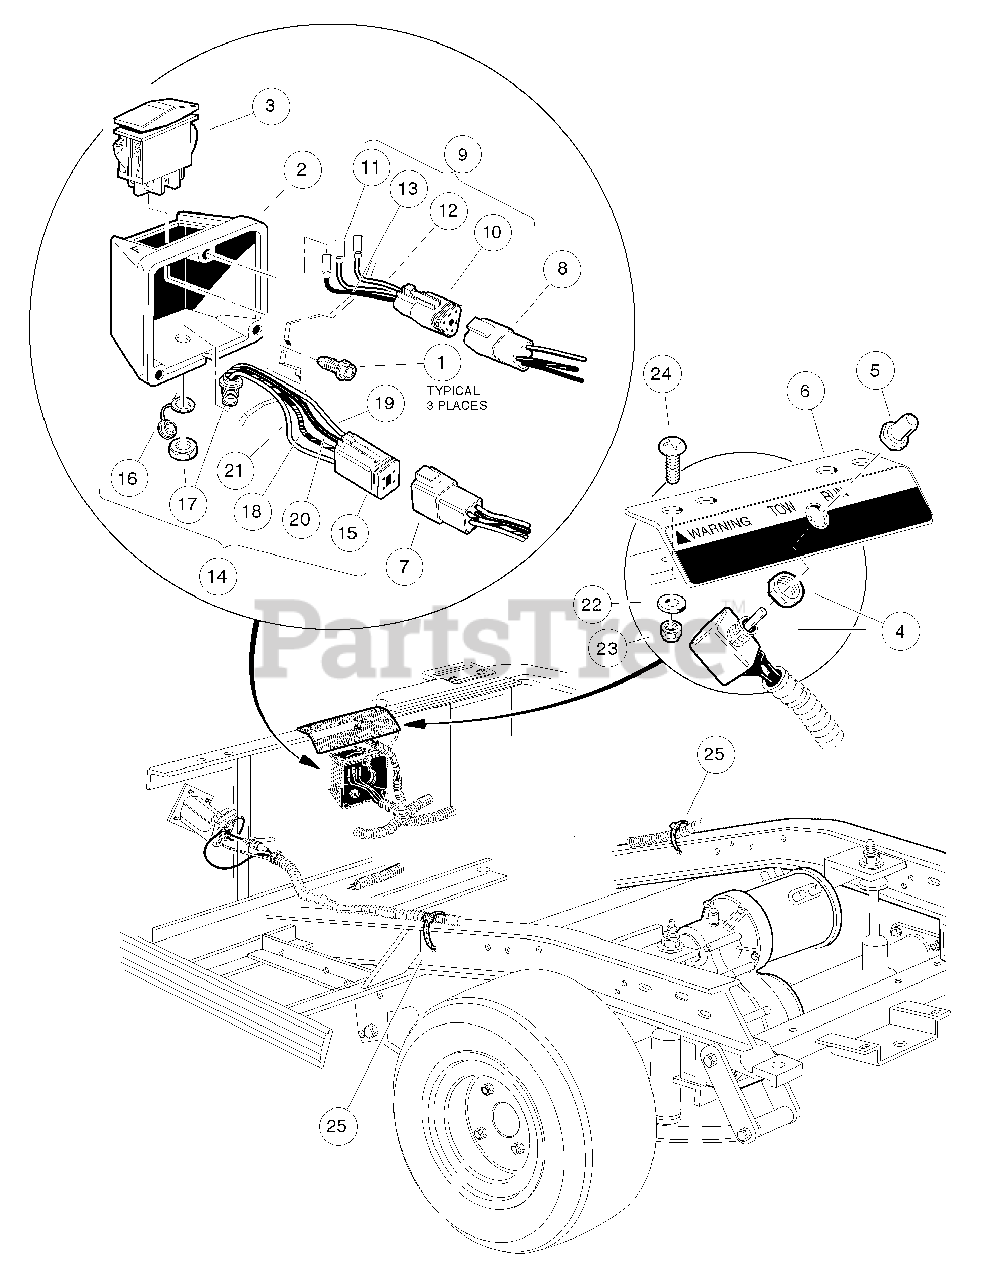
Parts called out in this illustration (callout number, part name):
1	Screw, 1/4 X 0.625 Hex-Head
2	Case, FNR Switch
3	Switch, Rocker, Single-Pole
4	Switch Assembly, Tow/Run
5	Boot, Switch
6	Bracket, Tow/Run Switch Mounting
7	Kit, 4-Pin Receptacle and Wedge Lock
8	Kit, 3-Pin Wedge Lock
9	Wire Assembly, FNR Switch
10	Kit, 3-Pin Wedge Lock
11	Wire Assembly, #18 Blue
12	Wire Assembly, #18 Orange
13	Wire Assembly, #18 Brown
14	Wire Assembly, IQDM Port
15	Kit, 4-Pin Wedge Lock
17	Connector Mount, Four-Pin
18	Wire Assembly, #18 Red/Yellow
19	Wire Assembly, #18 Black/Yellow
20	Wire Assembly, #18 Blue/Yellow
21	Wire Assembly, #18 Green/Yellow
22	Washer, 1/4 Type A Narrow Flat
23	Locknut, 1/4-20 Nylon Insert
24	Screw, 1/4-20 X 0.75 Truss-Head Machine
25	Tie Wrap, 8" Nylon
